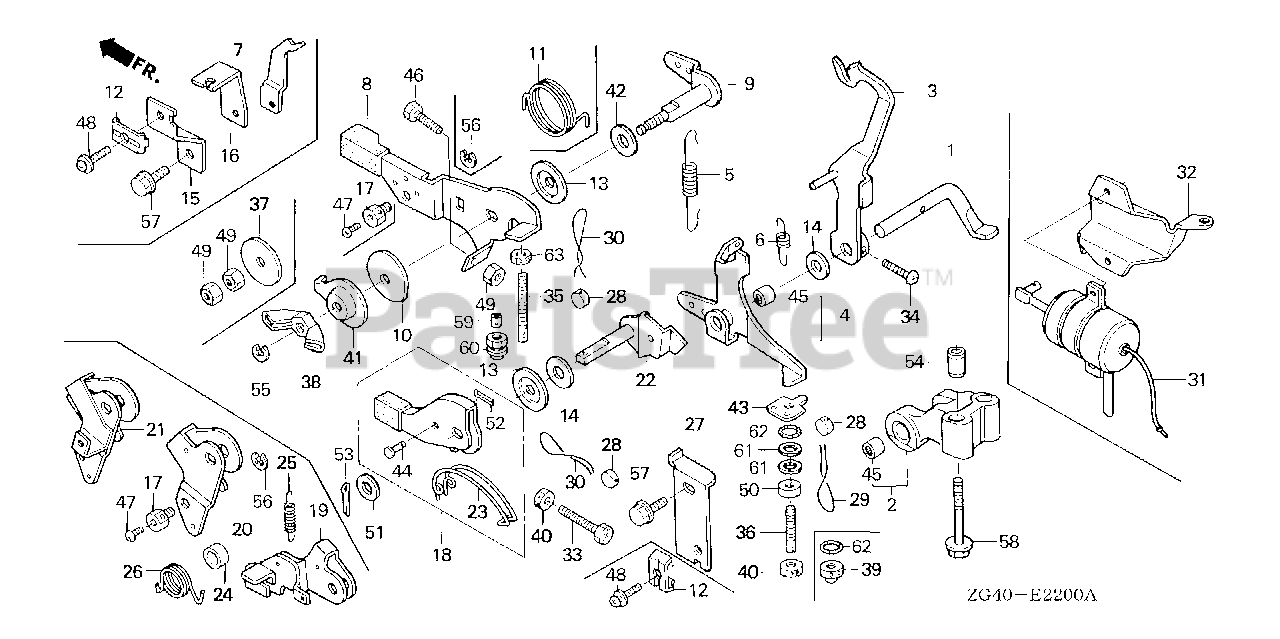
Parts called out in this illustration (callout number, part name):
1	SHAFT, GOVERNOR ARM
2	STAY, GOVERNOR SHAFT
3	ARM, GOVERNOR
4	ARM, SUB-GOVERNOR
5	SPRING, GOVERNOR
6	SPRING, IDLE
8	LEVER, CONTROL
9	SHAFT, CONTROL LEVER
10	SPRING, LEVER
13	SPACER, CONTROL LEVER (A)
14	SPACER, CONTROL LEVER (B)
18	LEVER, STOP
22	SHAFT, STOP LEVER
23	SPRING, STOP LEVER
27	HOLDER, STOP CABLE
29	WIRE, LOCK (A)
30	WIRE, LOCK (B)
33	BOLT, RECESSED (6X32)
34	SCREW, PAN (3X18)
35	BOLT, CONTROL ADJUSTING
36	BOLT, ADJUSTING (NOT AVAILABLE)
38	NUT, PLUG COVER
40	NUT, HEX. (6MM)
41	WASHER (6X30)
42	SPACER, CONTROL LEVER (B)
43	WASHER, SEALING
44	PIN, CENTER (4X16.5)
45	BEARING, NEEDLE (8X12X10) (TOYO)
46	BOLT, RECESSED (6X20)
49	NUT, HEX. (6MM)
50	NUT, HEX. (6MM)
51	WASHER, PLAIN (8MM)
52	PIN, SPLIT (1.6)
53	PIN, SPLIT (2.5X30)
54	PIN, DOWEL (8X14)
55	E-RING (3MM)
57	BOLT, FLANGE (6X16)
58	BOLT, FLANGE (6X40)
63	NUT, HEX. (6MM)
